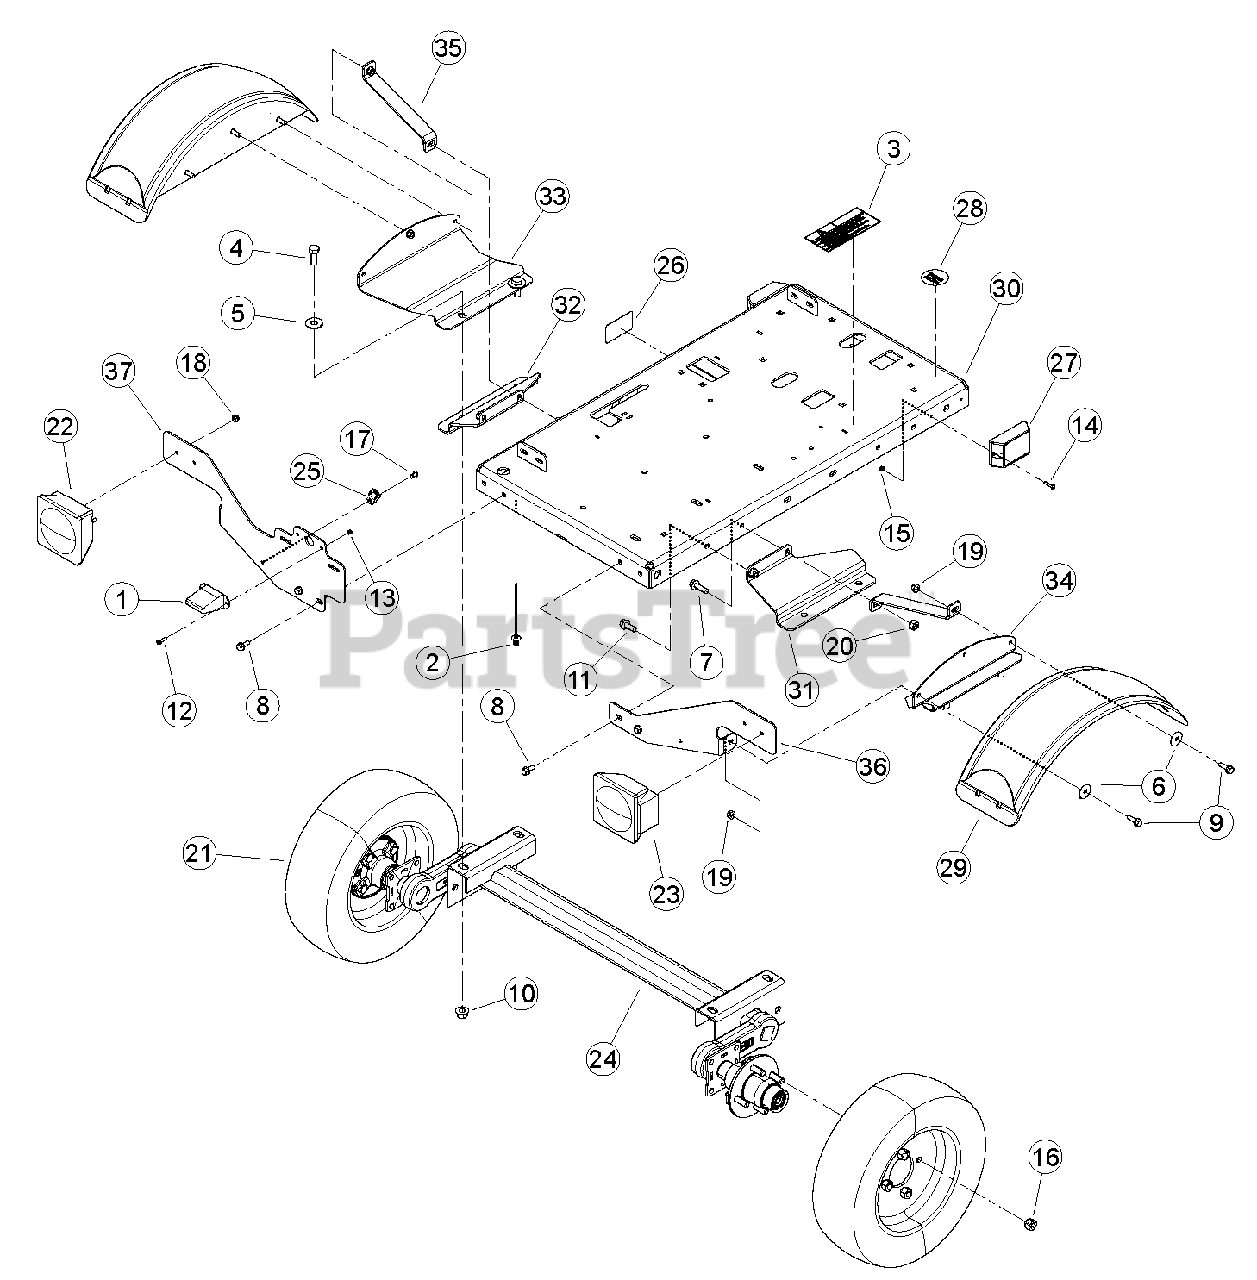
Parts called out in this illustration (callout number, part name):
1	LIGHT, LICENSE PLATE
2	TIE, DOME FIR TREE
3	DECAL, MUTILINGUAL MANUAL
4	BOLT, 1/2 X 1-1/4" GR5 HHCS NC ZP
5	WASHER, 1/2" FLAT ZP
6	WASHER, 5/16" FENDER ZP
7	BOLT, 3/8 X 1-1/4 FLANGE NC
8	BOLT, 5/16 X 3/4 FLANGE NC
9	BOLT, 5/16 X 1 FLANGE NC
10	NUT, 1/2-13 NYLOCK FLANGE
11	BOLT, 3/8 X 1 FLANGE NC
12	SCREW, #10 X 3/4 HEX TAP SC
13	NUT, 8-32 NYLOCK
14	SCREW, MCH 10-24 X 1" RND HD PHL ZP
15	NUT, 10/24 NYLOCK TYPE NM ZP
16	NUT, 1/2-20 WHEEL
17	RIVET, AL BLIND 1/4 X 3/4 DOME HEAD
18	NUT, 1/4-20 NYLOCK-FLANGE
19	NUT, 5/16-18 NYLOCK-FLANGE
20	NUT, 3/8-16 NYLOCK-FLANGE
21	ASSEMBLY, TIRE + WHEEL 4.80-8
22	LIGHT, LH TAIL
23	LIGHT, RH TAIL
24	AXLE, 1000LB TORSION
25	CLAMP, CABLE MOUNT
26	DECAL, 5.30-12 LOAD RATING
27	LIGHT, AMBER MARKER
28	DECAL, NATM COMPLIANCE
29	FENDER, BLACK PLASTIC DRILLED
30	WELDMENT, CHIPPER TRAILER
31	SUPPORT, AXLE FENDER RH
32	SUPPORT, AXLE FENDER LH
33	SHEET, MOUNT FENDER LH
34	SHEET, MOUNT FENDER RH
35	BRACKET, FENDER SUPPORT
36	BRACKET, LIGHT RH
37	BRACKET, LIGHT LH
